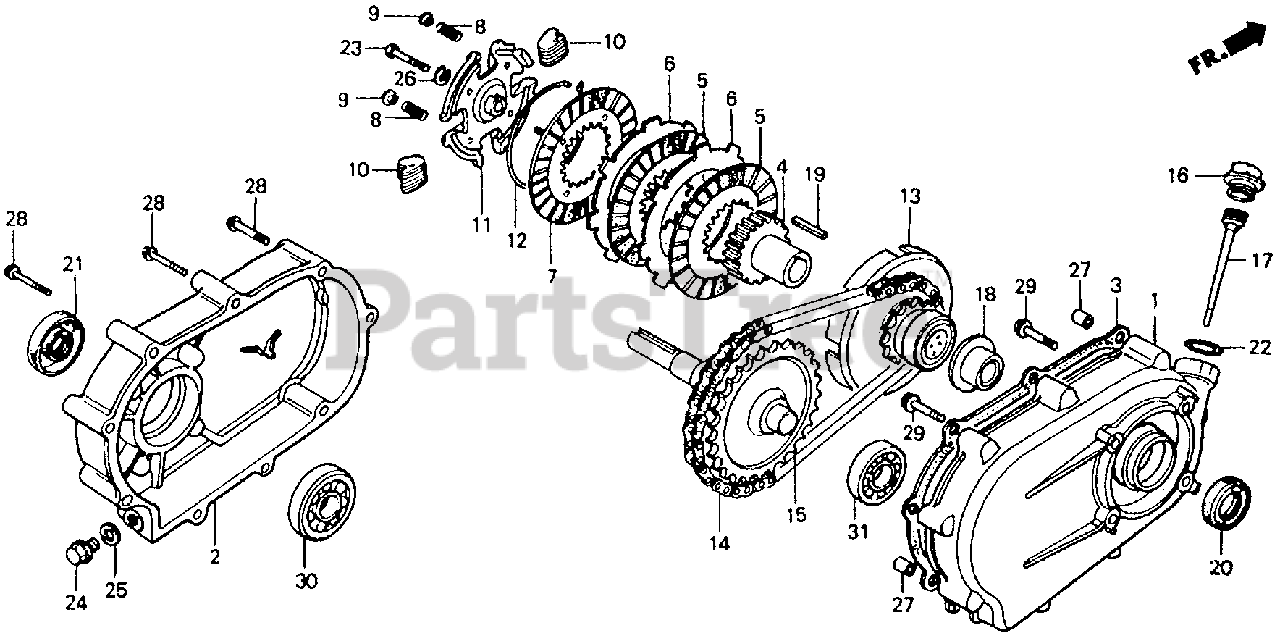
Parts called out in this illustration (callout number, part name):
1	CASE, REDUCTION
2	COVER, REDUCTION
3	GASKET, REDUCTION COVER
4	CENTER, CLUTCH
5	DISK, CLUTCH FRICTION
6	PLATE, CLUTCH
7	PLATE, CLUTCH PRESSURE
8	SPRING, CLUTCH FREE
9	HOLDER, CLUTCH SPRING
10	WEIGHT, CLUTCH
11	HOLDER, CLUTCH WEIGHT
12	CENTER, CLUTCH WEIGHT
13	SPROCKET, DRIVE (14T)
14	CHAIN, DRIVE (RK428SH-36LE)
15	SHAFT, P.T.O. (28T)
16	CAP, REDUCTION OIL
17	DIPSTICK, OIL
18	WASHER, THRUST (25MM)
19	KEY, CLUTCH CENTER
20	OIL SEAL (30X46X8)
21	OIL SEAL (PJ30507)
22	O-RING (26X2.7)
23	BOLT, HEX. (8X35)
24	BOLT, DRAIN PLUG (12MM)
25	WASHER, DRAIN PLUG (12MM)
26	WASHER, SPRING (8MM)
27	PIN A, DOWEL (8X14)
28	BOLT, FLANGE (6X50)
29	BOLT, FLANGE (8X32)
30	BEARING, RADIAL BALL (6205)
31	BEARING, RADIAL BALL (6206)
